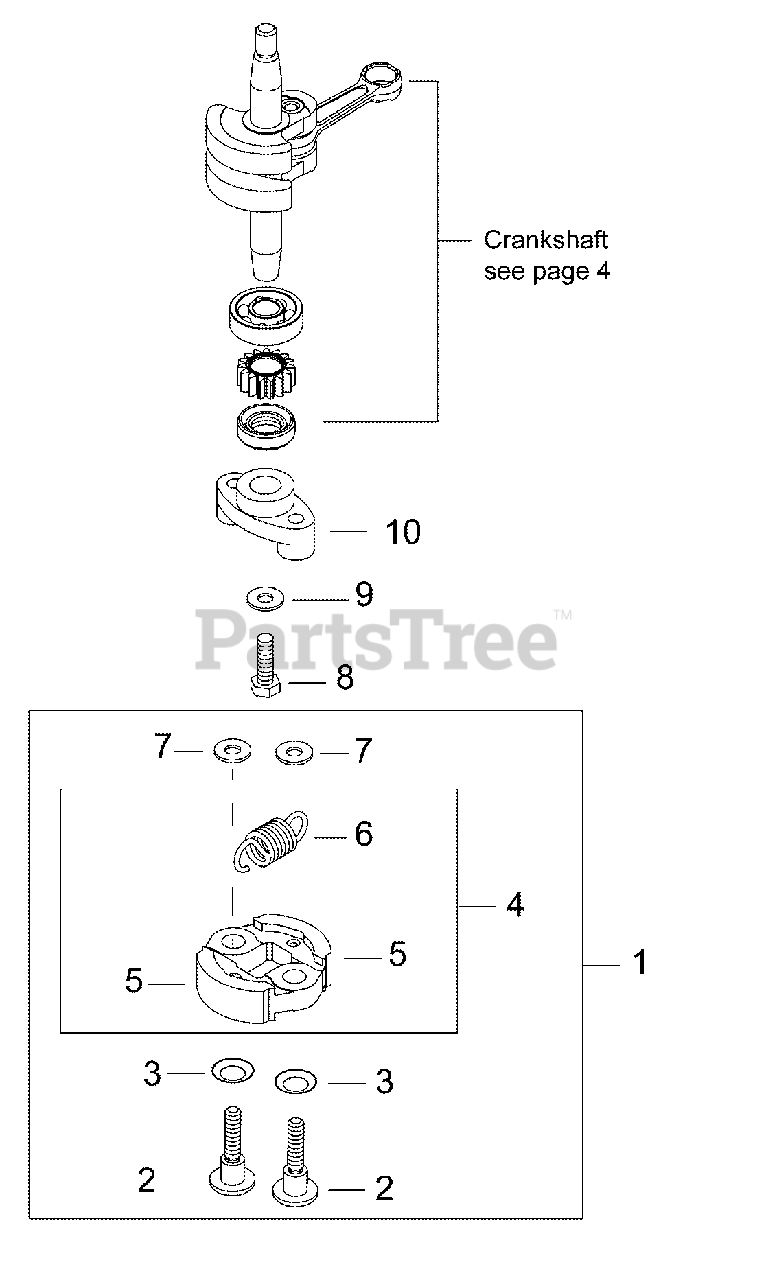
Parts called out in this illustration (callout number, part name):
1	CLUTCH KIT
2	BOLT, CLUTCH
3	WASHER, SPRING
4	SHOE ASSY, CLUTCH
5	SHOE, CLUTCH
6	SPRING, CLUTCH
7	WASHER 6 MM
8	BOLT M6×18
9	WASHER 6 MM
10	BOSS, CLUTCH
